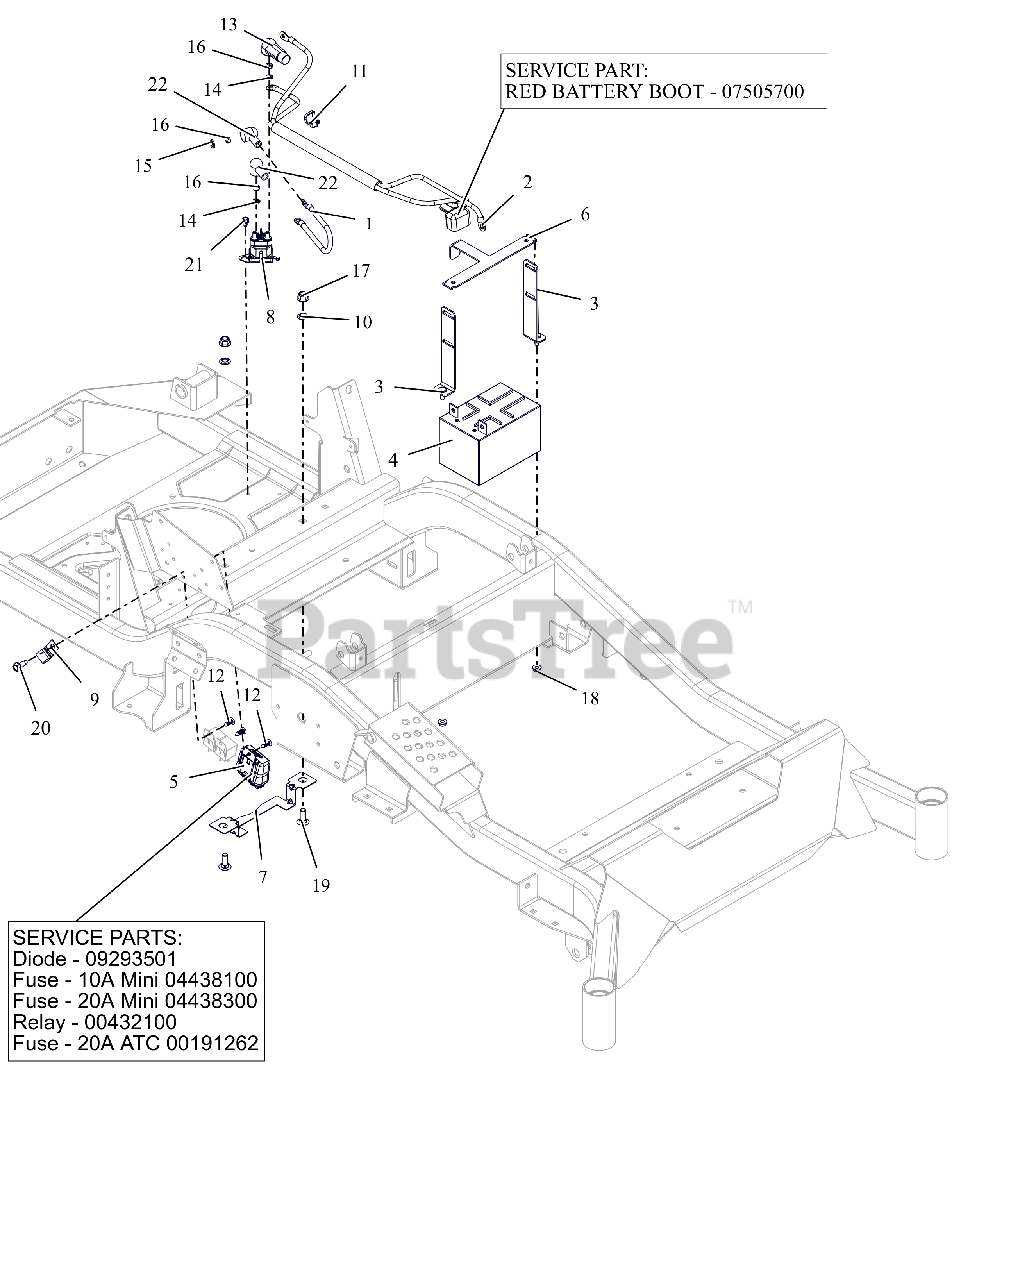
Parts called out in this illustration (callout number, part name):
1	CABLE, POS W/(2)1/4 RING 9.0LG
2	HARNESS, BATTERY HD
2	INSULATOR
3	WMT,BATTERY MOUNT HOLD DOWN
4	BATTERY, 12V 12A-190CCA
5	HARNESS, WIRE
5	DIODE, CONNECTOR SHELL
5	FUSE,10 AMP MINI-ATC
5	FUSE,20 AMP MINI ATC
5	RELAY,SEALED W/DIODE
5	FUSE, 20 AMP BLADE S/O
6	BRKT, BATTERY TIE DOWN
7	GUARD, ELECTRICAL HARNESS
8	SOLENOID, STARTER (SEALED)
9	J-CLAMP
10	NUT-PUSH .38 DIA. PAL ZINC
11	CABLE TIE W/ TREE (.25 HOLE)
12	RIVET, .25 NYLON PANEL
13	BOOT, .65ID POS
14	WSHR,LK-EXT.262X.502X.026 ZCC
15	WSHR,LK-REG .312X.078 ZCC
16	NUT-STD M6-1.0 ZCC
17	NUT,NYL-FLG .38-16 GF ZCC
18	NUT-LK-TOP-FLG .250-20 GF ZCC
19	BLT, RHSN .38-16X1.00 G5 ZCC
20	SCR,TAP .312-18X.75 HWH TR ZCC
21	SCR,TAP .25-20X.375 HWH TR ZCC
22	BOOT, EYELET TERMINAL
